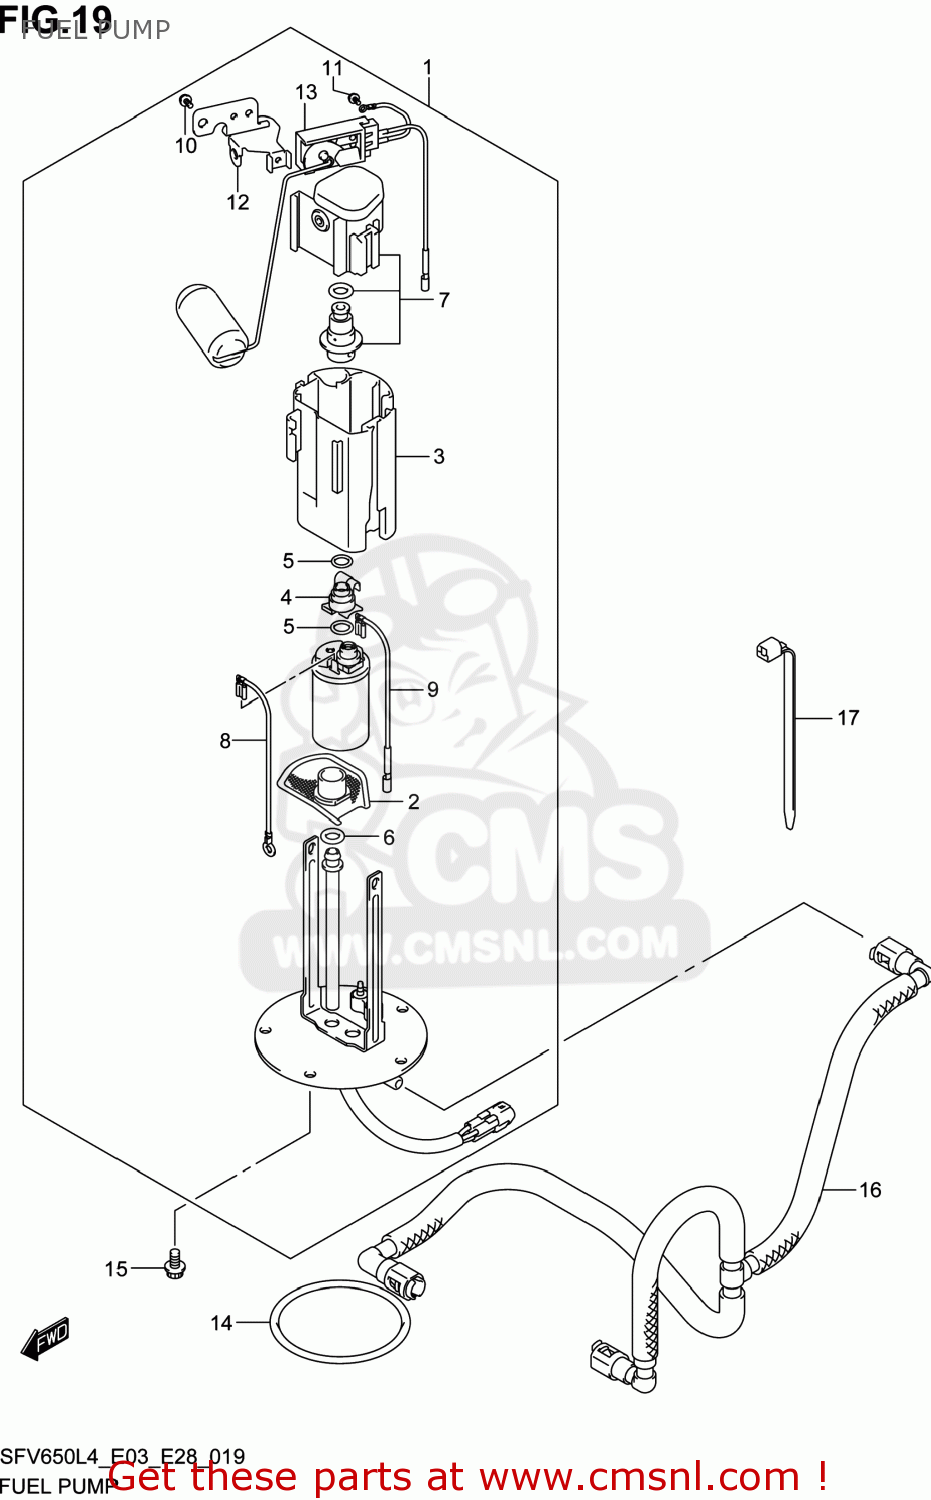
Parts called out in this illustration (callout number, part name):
1	PUMP ASSY,FUEL
2	STRAINER
3	CUP
4	JOINT
5	O RING
6	O RING
7	REGULATOR
8	WIRE,EARTH
9	WIRE,LEAD
10	SCREW
11	SCREW
12	BRACKET,FUEL GAUGE
13	GAUGE ASSY
14	O RING,FUEL PUMP
15	BOLT
16	HOSE,FUEL
17	CLAMP(L:165)
